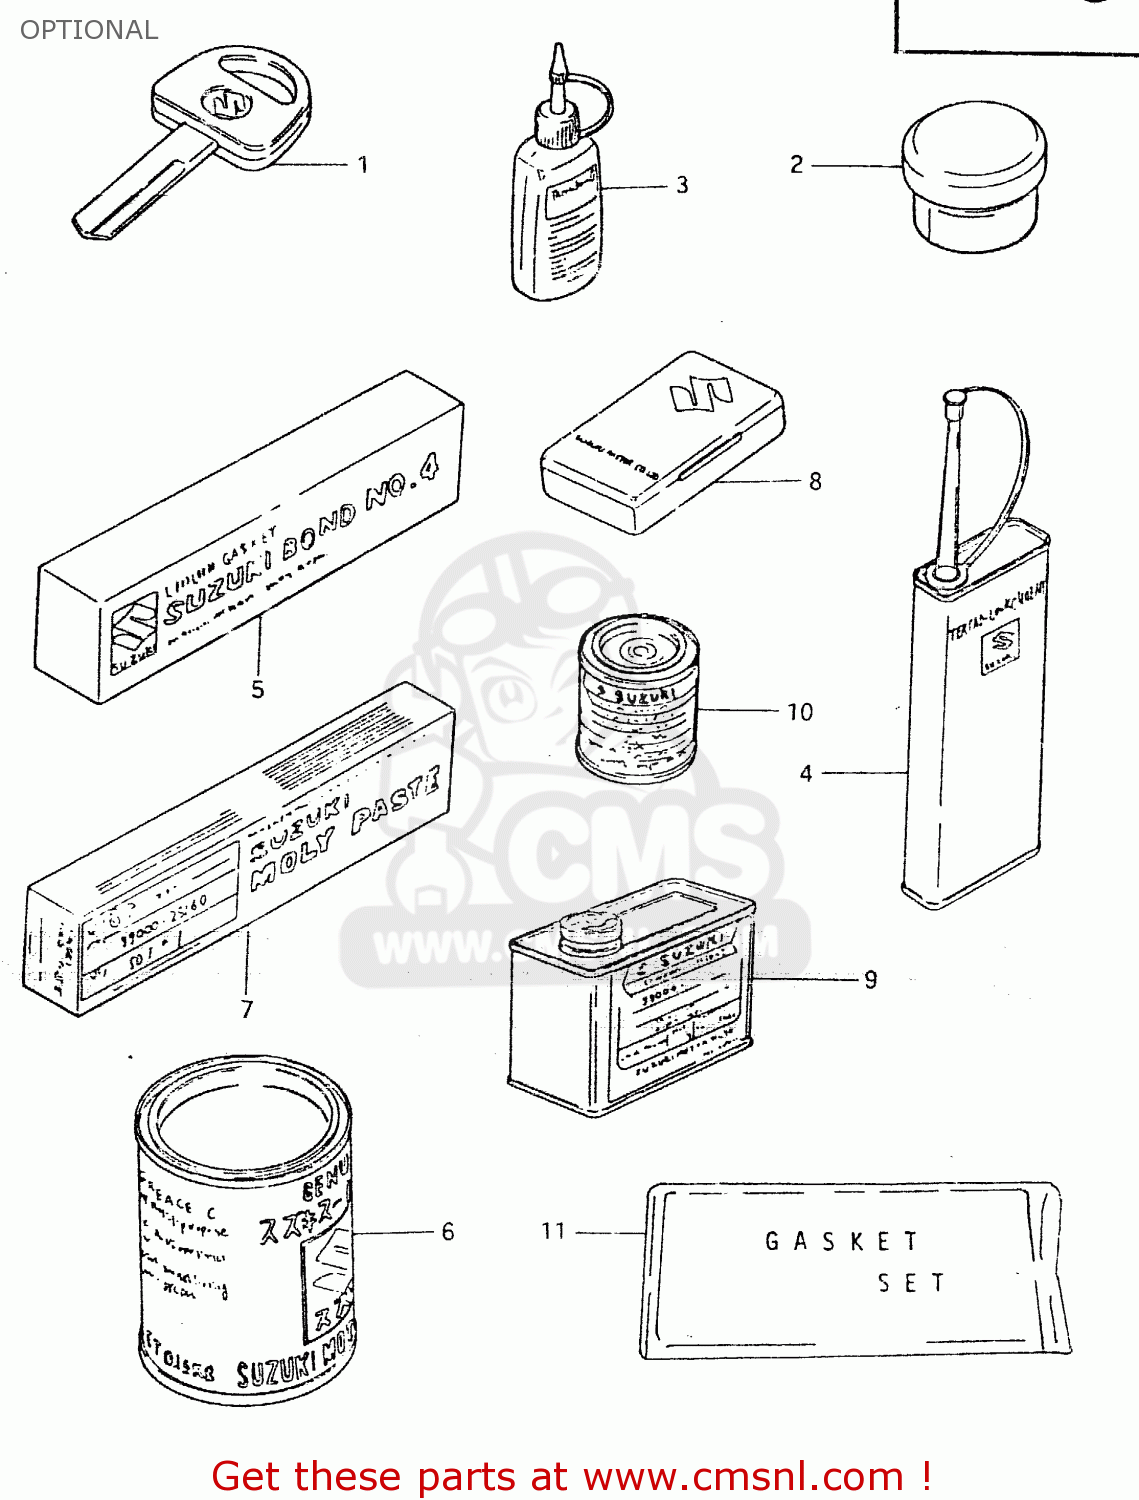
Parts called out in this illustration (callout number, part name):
1	KEY,BLANK
2	GREASE,PBC FOR BRK PAD 20G
3	THREAD LOCK SUPER (1332B)
4	THREAD LOCK NO.1401 CLEAR 200G
5	BOND 1104
6	GREASE(C)EP2 LITHIUM 150G
7	SUZUKI MOLY PASTE
8	TUBE REPARING TOOL
9	PAINT (BLACK)
10	PAINT,BLACK
11	GASKET SET
